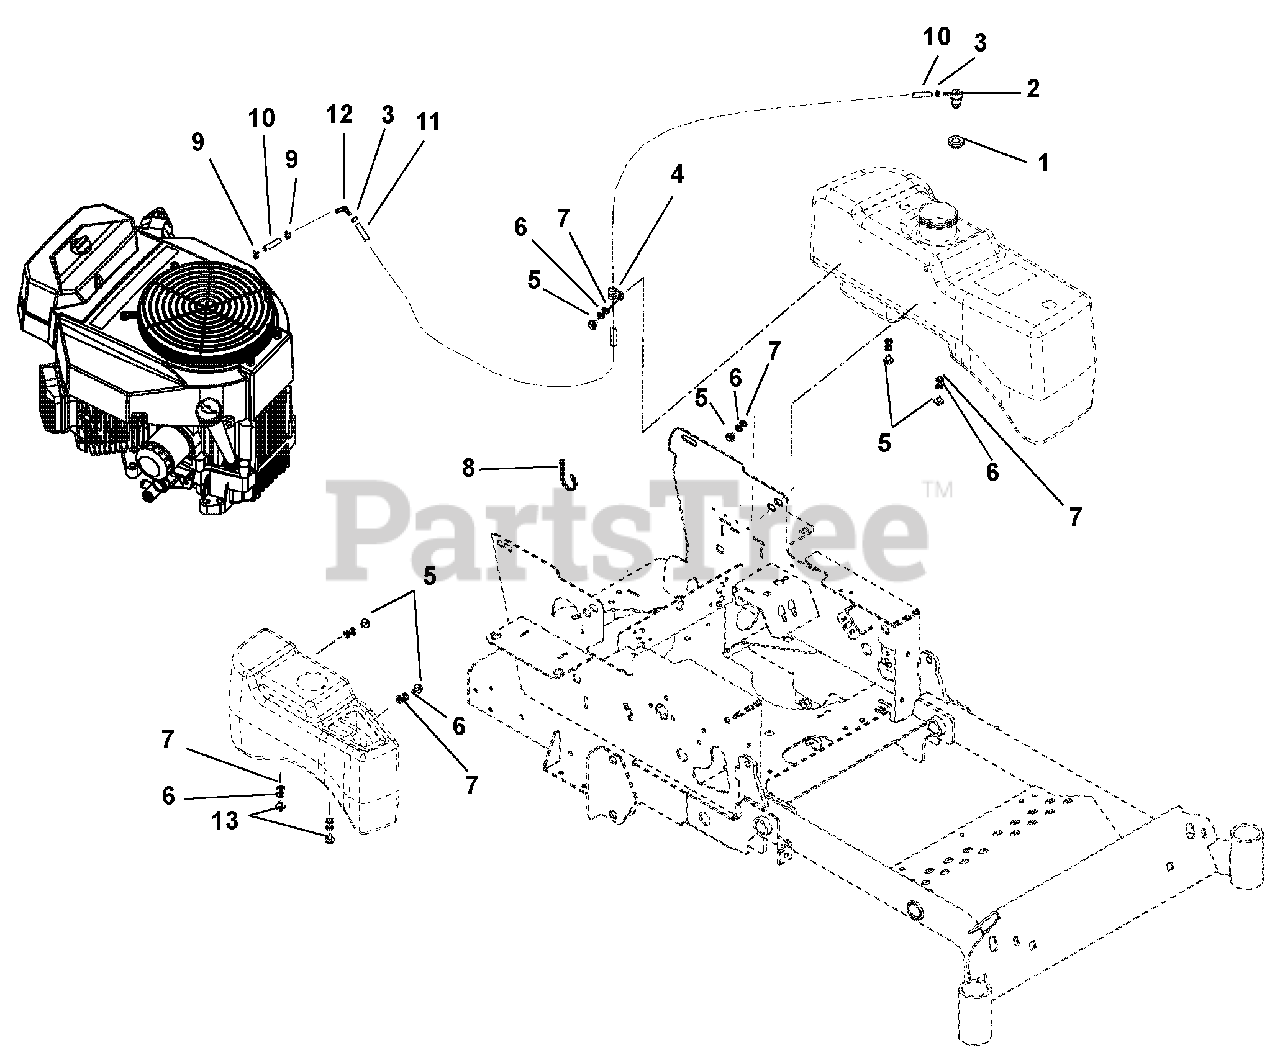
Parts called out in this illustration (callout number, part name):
2	Valve
3	Hose, Clamp
5	Bolt, .31-18 x .62
6	Washer, Locking .31 x .078 Regular
7	Washer, Flat Steel .38 x .875 x .083
8	Tie, Cable LG 5.50
9	Clamp, Spring .188
10	Hose, Fuel, .18
11	Hose, Fuel, .25
12	Fitting, 90° Vacuum .18 x .25
13	Screw, Plastite .25-10 x .75 YZ
